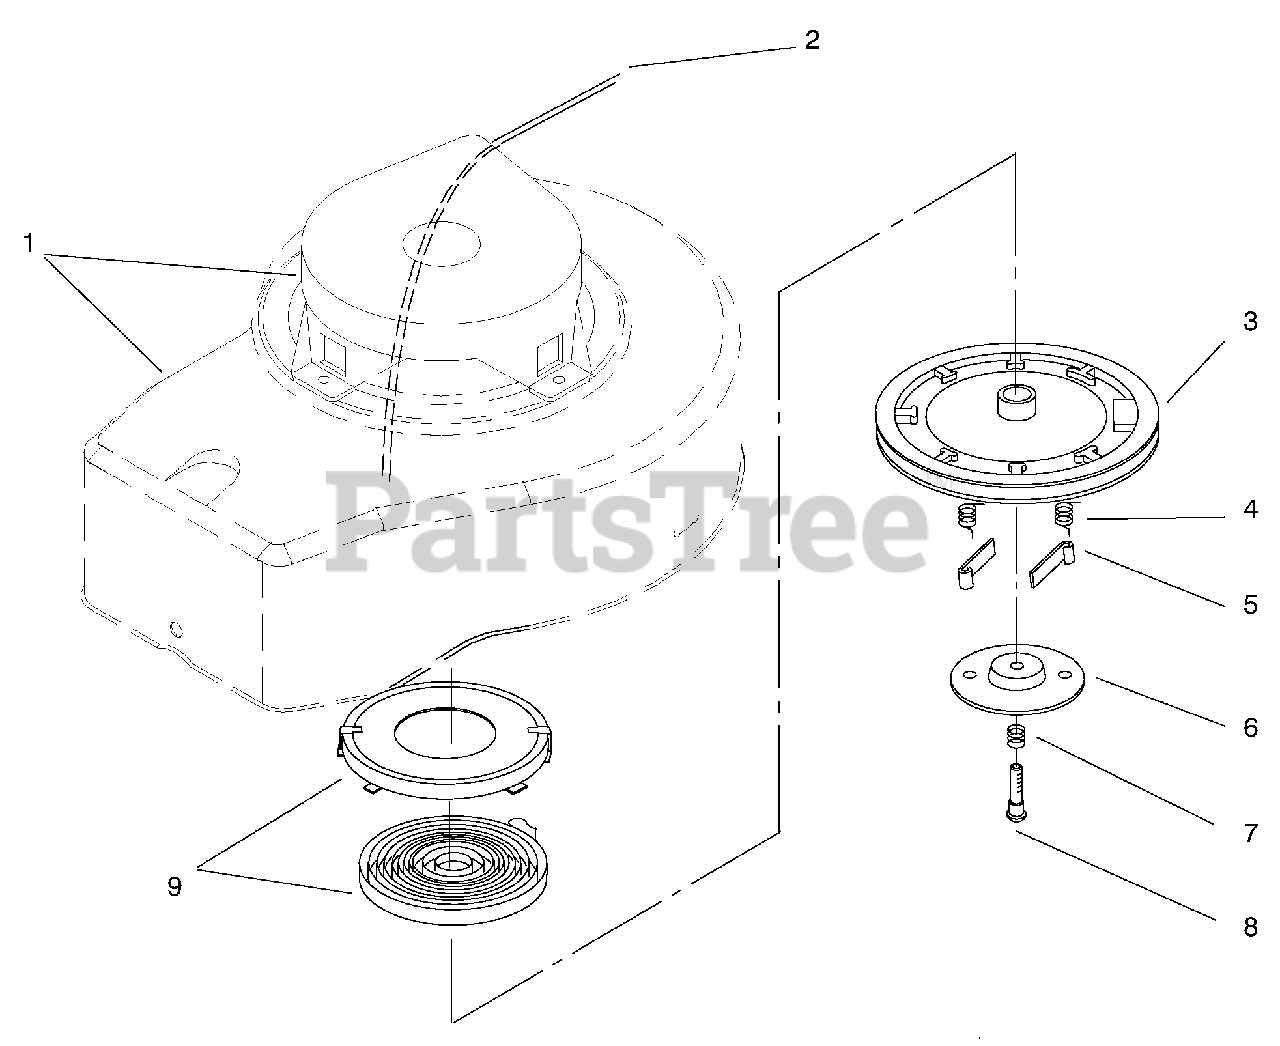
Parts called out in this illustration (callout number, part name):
1	Housing Assembly
2	Rope-Starter
3	Pulley Assembly
4	Spring-Dog
6	Retainer
9	Spring Keeper Assembly
